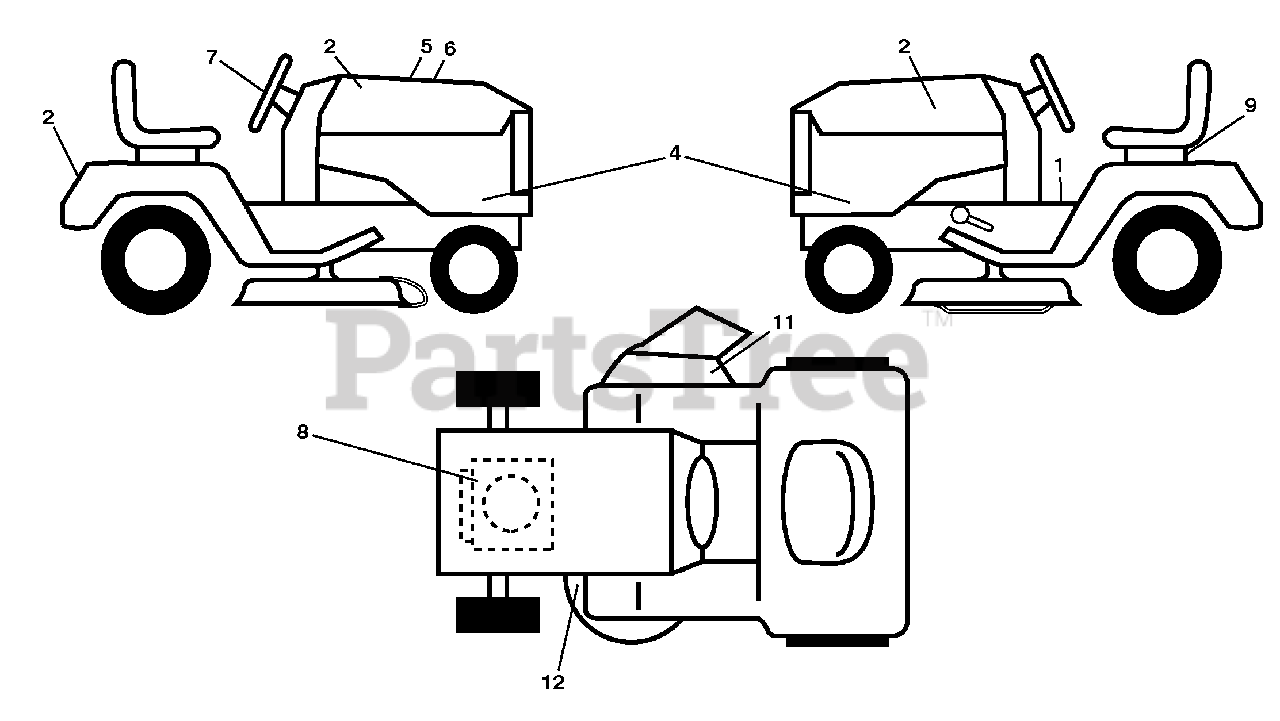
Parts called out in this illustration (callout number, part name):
1	Decal, Fender Warning
2	Decal, Hood
4	Decal, Hood Panel
5	Decal, Customer Respons.
6	Decal, Replacement
7	Decal, Steering Wheel
8	Decal, Eng. BS
9	Decal, Battery Dnge/Poi
11	Decal, Warning
12	Decal, Mower V-Belt Schematic
